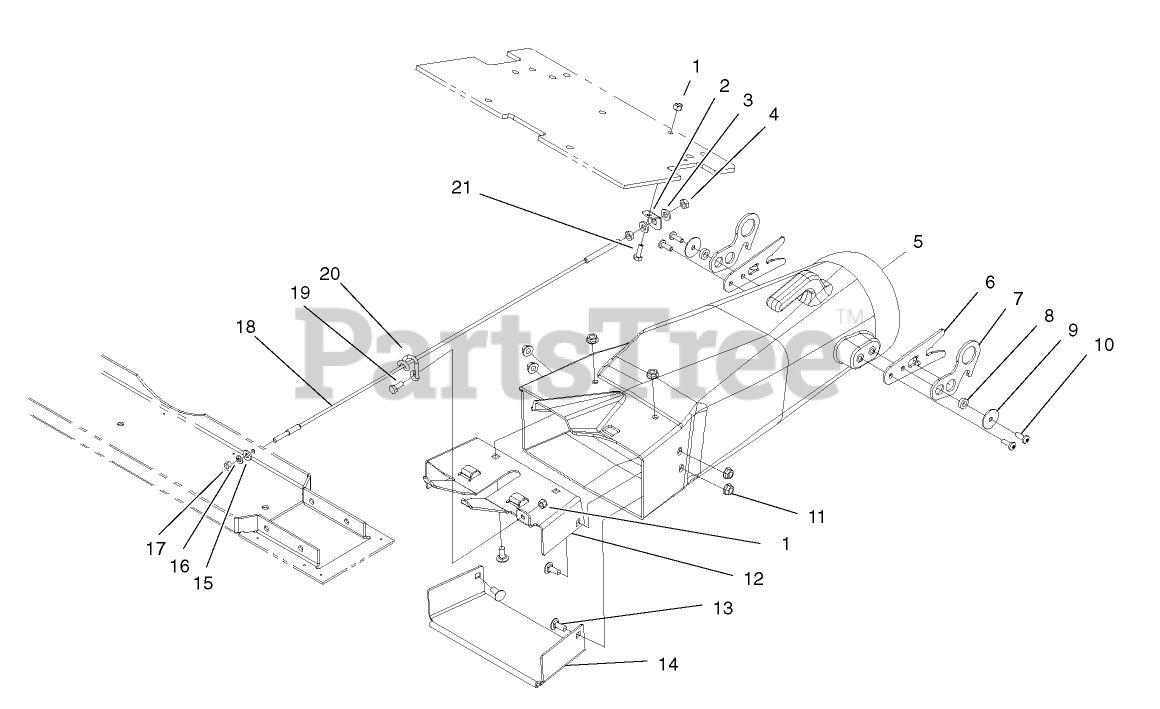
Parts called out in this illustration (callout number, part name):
1	NUT-LOCK, NI
2	BRACKET-SPRING
3	WASHER-PLAIN
4	NUT-JAM
5	PLENUM
6	PLATE-GUIDE
7	PLATE-LATCH
8	SPACER
9	WASHER-FLAT
10	SCREW-TORX
11	NUT-HF
12	PLATE-PLENUM, TOP
13	SCREW-CARR
14	PLATE-PLENUM, BOTTOM
15	WASHER-FLAT
16	WASHER-LOCK
17	NUT-HEX
18	CABLE-TENSION
19	SCREW-HH
20	GUIDE-CABLE
21	SCREW-HH
